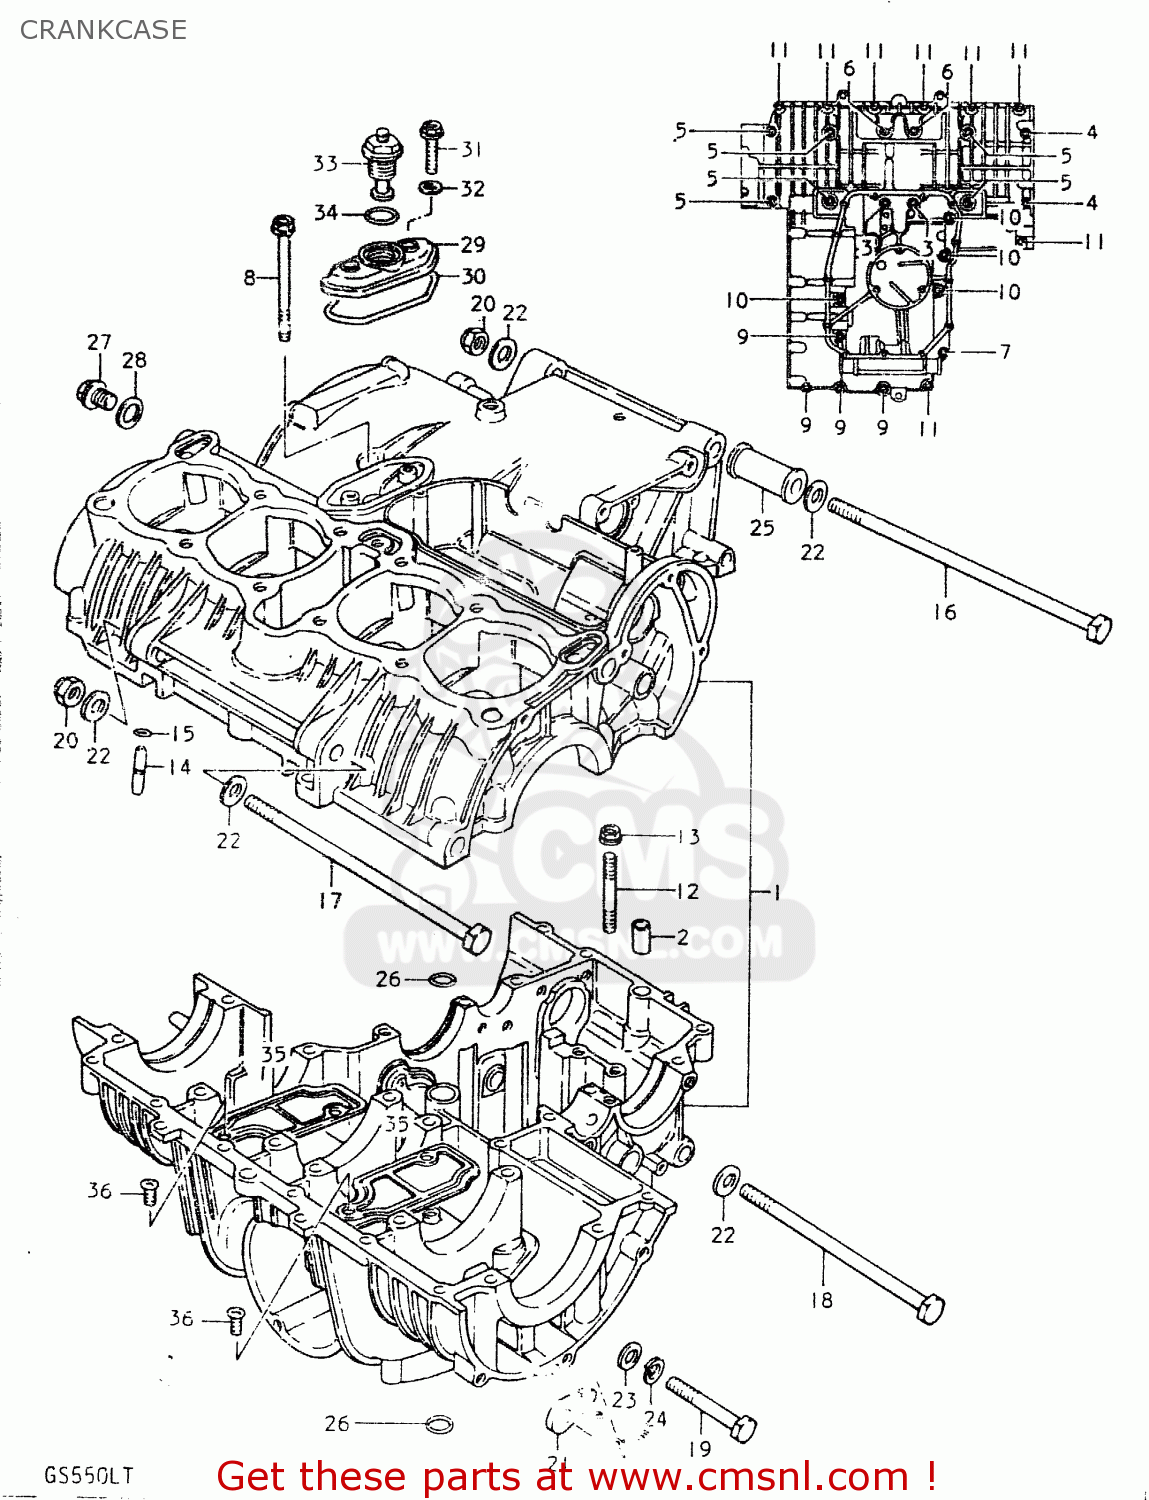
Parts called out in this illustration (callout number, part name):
1	CRANKCASE SET
2	PIN
3	BOLT
4	BOLT 8X90
5	BOLT (8X70)
6	BOLT 8X55
7	BOLT (8X45)
8	BOLT (6X90)
9	BOLT (6X60)
10	BOLT ,6X50
11	BOLT
12	STUD BOLT
13	NUT
14	UNION
15	O-RING
16	BOLT 10X270
17	BOLT
18	BOLT(10X165)
19	BOLT 10X55
20	NUT
21	NUT
22	WASHER
23	WASHER(10.5X20X3.2)
24	LOCK WASHER
25	SPACER,ENGINE MOUNT
26	O RING(D:3.2,ID:12.9)
27	PLUG (14X12)
28	GASKET(14X19.2X2) (NAS)
29	HOUSING,OIL PRESSURE SWITCH
30	O RING,PRESSURE SWITCH HOUSING
31	BOLT
32	GASKET (NAS)
33	SWITCH ASSEMBLY
34	O RING(D:1.9,ID:18.8)
35	PLATE,OIL SEPARATOR
36	SCREW
